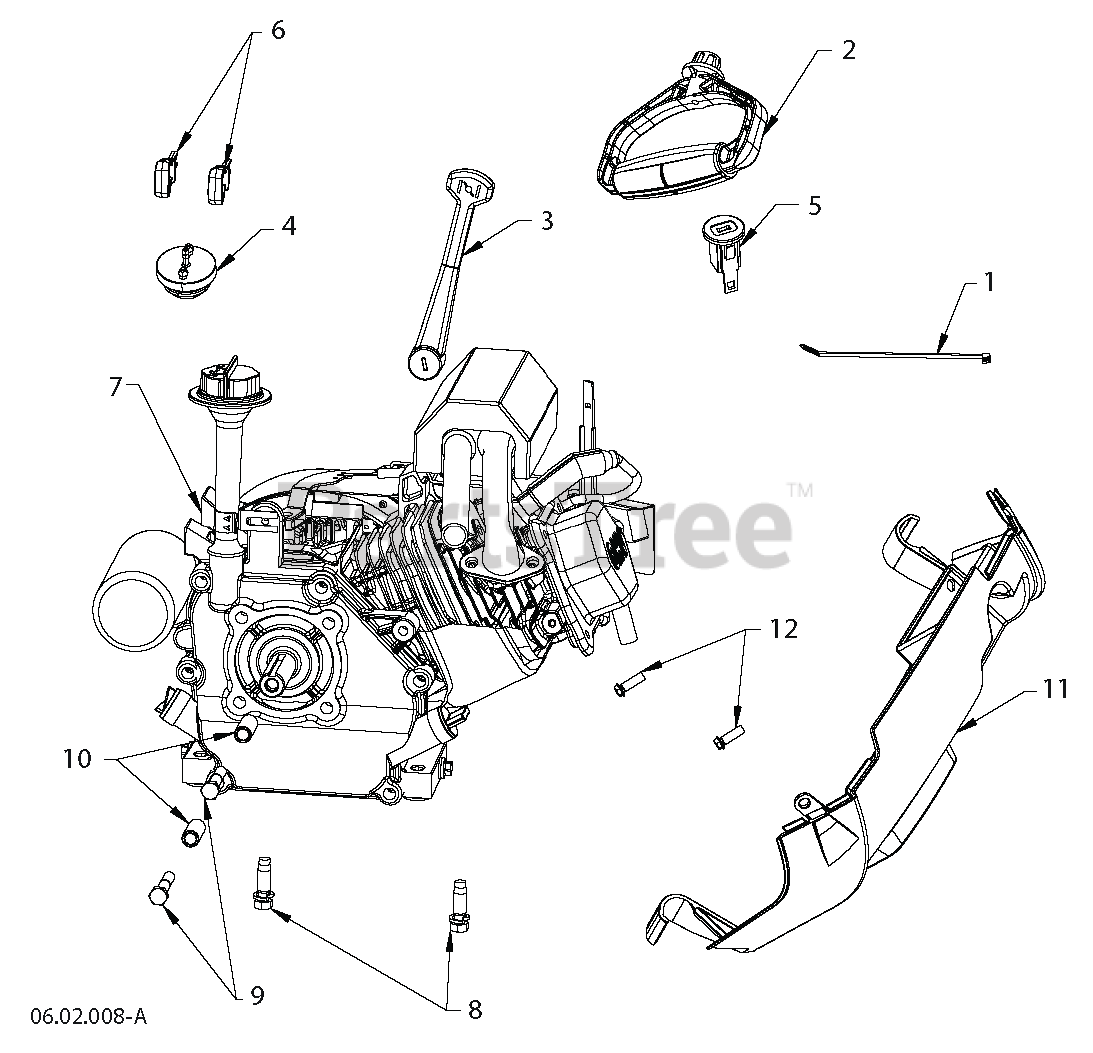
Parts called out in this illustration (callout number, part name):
1	WIRE.TIE
2	HANDLE.STARTER.SNOW
3	LEVER.CHOKE
4	RP BULB.PRIMER
5	KEY HOUSING
6	KEY.SINGLE.STAGE.HUSQVARNA
8	BOLT 3/8-16X1-1/8
9	SCREW. 5/16-24 X 2.00"HHCS
10	SPACER.ENGINE
11	COVER.REAR.LOWER.SSST.HUSQ.GRE
12	SCREW.HX.13X.750
